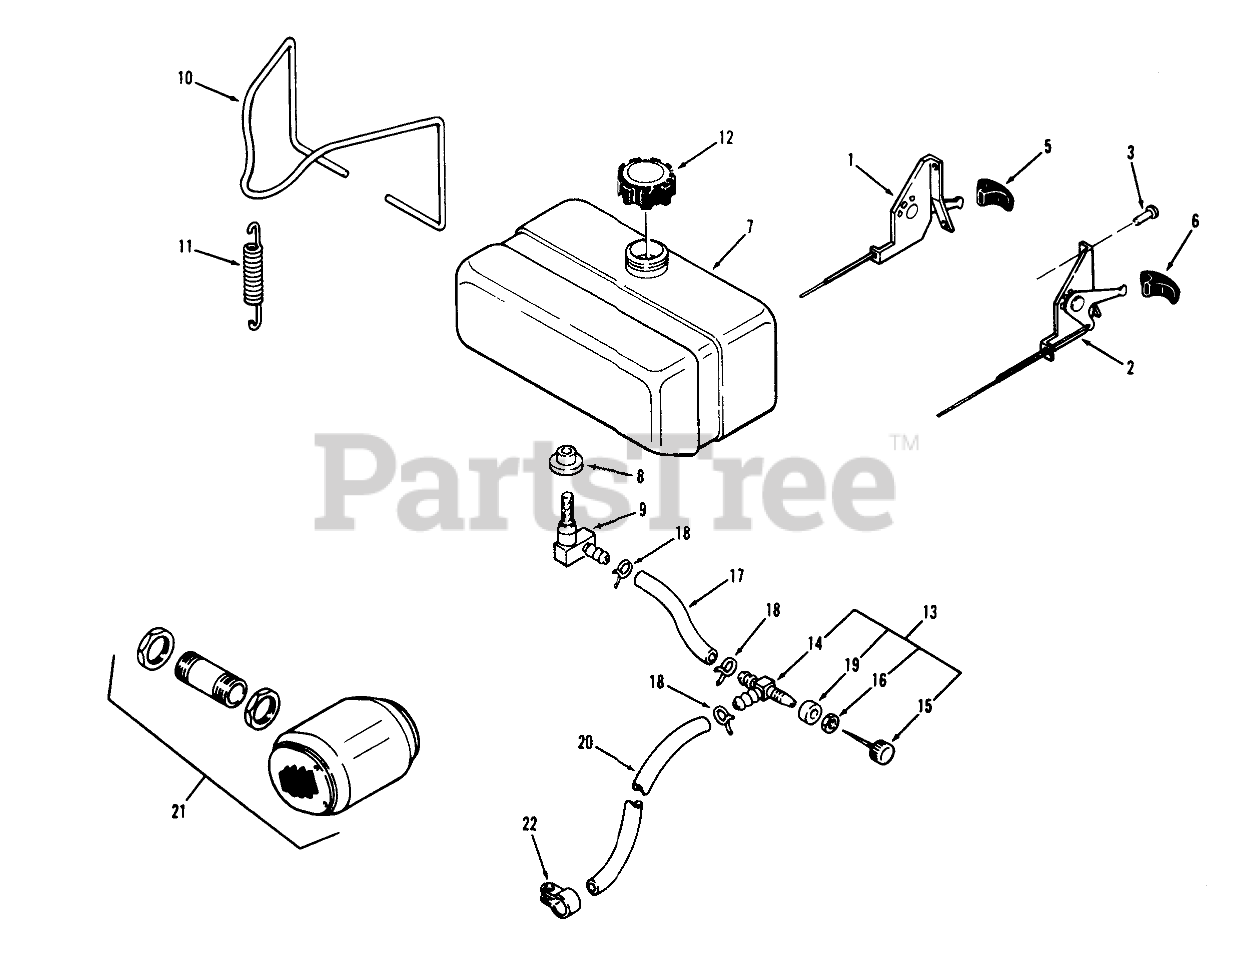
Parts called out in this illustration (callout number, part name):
1	Throttle Control
2	Control-Choke
3	RIVET-4
5	KNOB-THROTTLE
6	KNOB-CHOKE
7	ASSY-FUEL TANK
8	BUSHING
9	FITTING FUEL TANK
10	Hold Down Wire
11	SPRING-EXTENSION
12	Cap
13	S/A FUEL VALVE
14	VALVE BODY
17	Fuel Hose 4.5"
18	Clamp
19	SPACER
20	Fuel Hose 18"
21	Assy-Exhaust
22	CLAMP-HOSE
